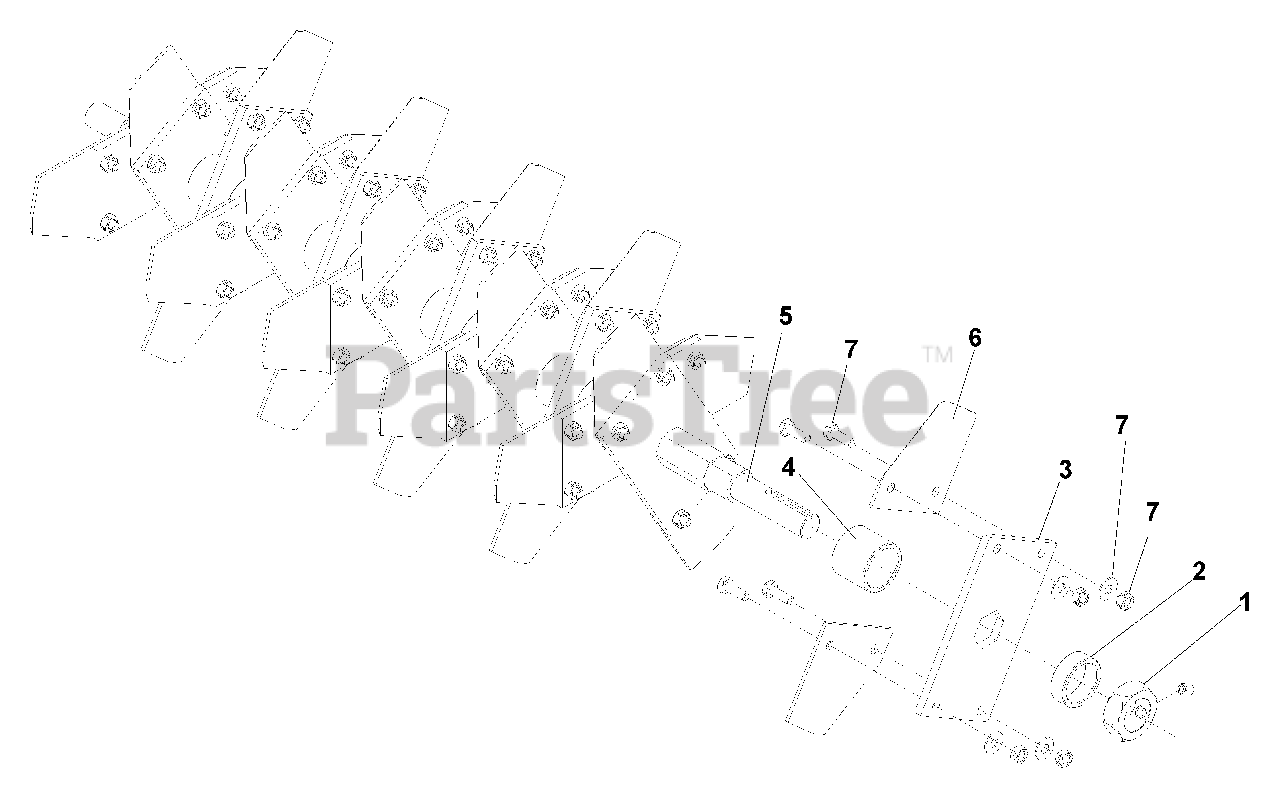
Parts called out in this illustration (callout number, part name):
1	JAM NUT W/SETSCREW
2	END SPACER
3	BLADE MTG PLATE
4	SPACER - LONG
6	BLADE W/HARDWARE SET (30 BLADES)
7	SCREW & NUT SET (60 EACH)
